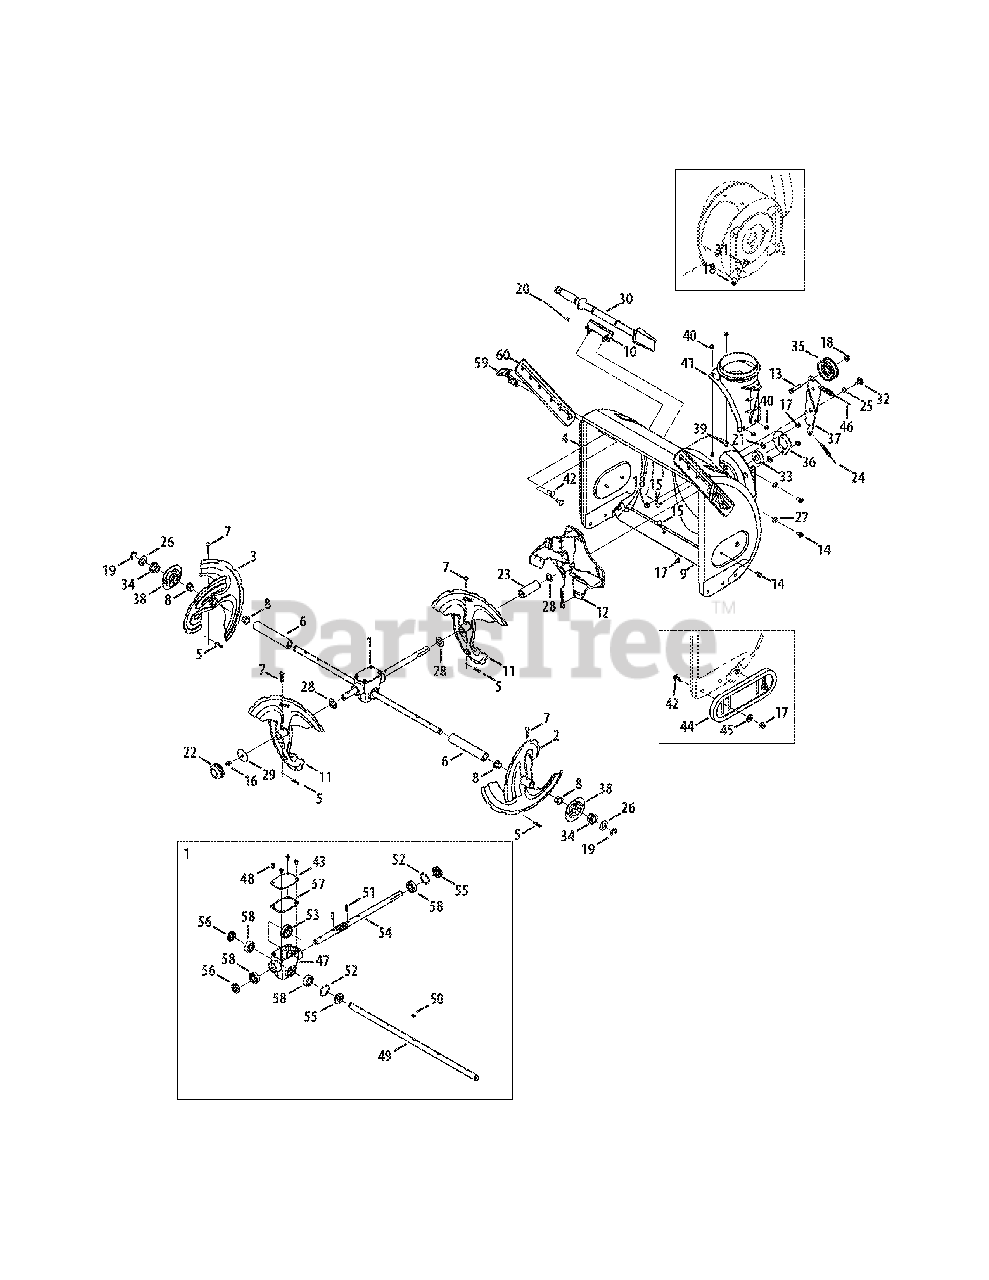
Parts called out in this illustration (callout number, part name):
1	Gearbox Assembly, Auger
2	Spiral Assembly - LH
3	Spiral Assembly - RH
4	Auger Housing, 24"
5	Bow Tie Cotter Pin
6	Spacer, 1.25 OD x .75 ID x 5.8
7	Shear Pin
8	Flange Bushing, .800 x .910
9	Shave Plate, 24"
10	Clean-out Tool Mtg. Bracket
11	Accelerator Assembly
12	Impeller Assembly
13	Hex Bolt, 3/8-16 x 1.75
14	Screw, 5/16-18 x .750
15	Carriage Bolt, 5/16-18 x .750
16	Hex Washer Screw, 5/16-18 x .500
17	Flange Lock Nut, 5/16-18
18	Flange Lock Nut, 3/8-16
19	E-ring, .75
20	Cable Tie
21	Push-On Nut, .25 Dia.
23	Spacer, 1.35 OD x .76 ID x 2.705
24	Extension Spring, .38 OD x 4.59
25	Wave Washer, .625 x .885 x .0175
26	Flat Washer, .76 x 1.49 x .06
27	Bell Washer, .340 x .872 x .060
28	Flat Washer, .793 x 1.24 x .06
29	Flat Washer, .406 x 1.92 x .060
30	Clean-Out Tool
31	Shoulder Screw, 3/8-16 x .496 x .336
32	Shoulder Screw, 3/8-16 x .625 x .17
33	Flange Ball Bearing, .75 x 1.85
34	Hex Flange Bearing, .75 ID
35	Flat Idler Pulley
36	Bearing Housing
37	Auger Idler Bracket
38	Bearing Housing
39	Carriage Screw, 1/4-20 x 0.75
40	Flange Lock Nut, 1/4-20
41	Chute Adapter
42	Spacer, Carriage, 5/16-18 x 1.00
43	Gearbox Cover
44	Polymer Slide Shoe, Deluxe
44	Polymer Reversible Shoe Kit
45	Washer, Flat, .349 x .879 x .063
46	Auger Clutch Cable
47	Auger Housing
48	Screw, 1/4-20 x 0.75
49	Axle, Auger, 24"
50	Hi-Pro Key
51	Pin, Roll, .25 x 1.0
52	Retainer Ring
53	Worm Gear, 20T
54	Worm Shaft
55	Seal, .75 x 40mm x .25
56	Seal, .75 x 1.375 x .25
57	Gearbox Gasket
58	Ball Bearing, .75 x 40 x 12
59	Wing Knob
60	Drift Cutter
